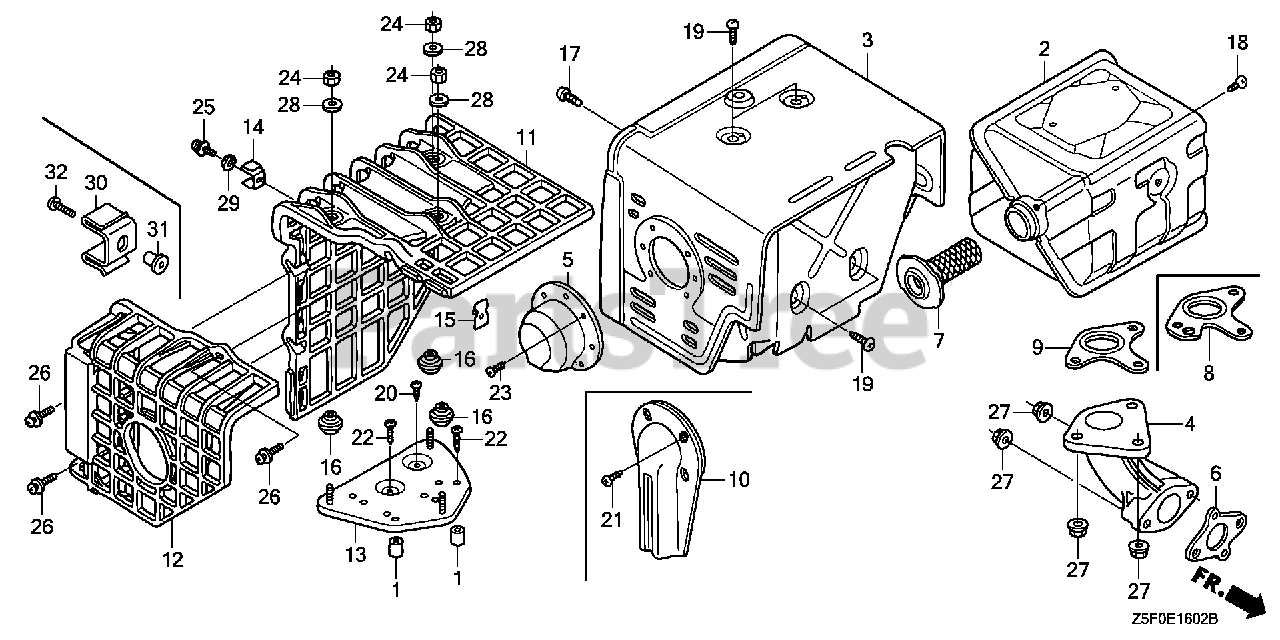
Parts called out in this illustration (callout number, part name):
2	MUFFLER (100DB)
3	PROTECTOR, MUFFLER
6	GASKET, EX. PIPE
7	ARRESTER, SPARK
8	GASKET, MUFFLER (ARRESTER)
17	SCREW, TAPPING (6X10)
18	SCREW, TAPPING (5X8)
18	SCREW, TAPPING (4X6) (TO INSTALL OPTIONAL SPARK ARRESTER)
19	SCREW, TAPPING (5X8)
27	NUT, FLANGE (8MM)
